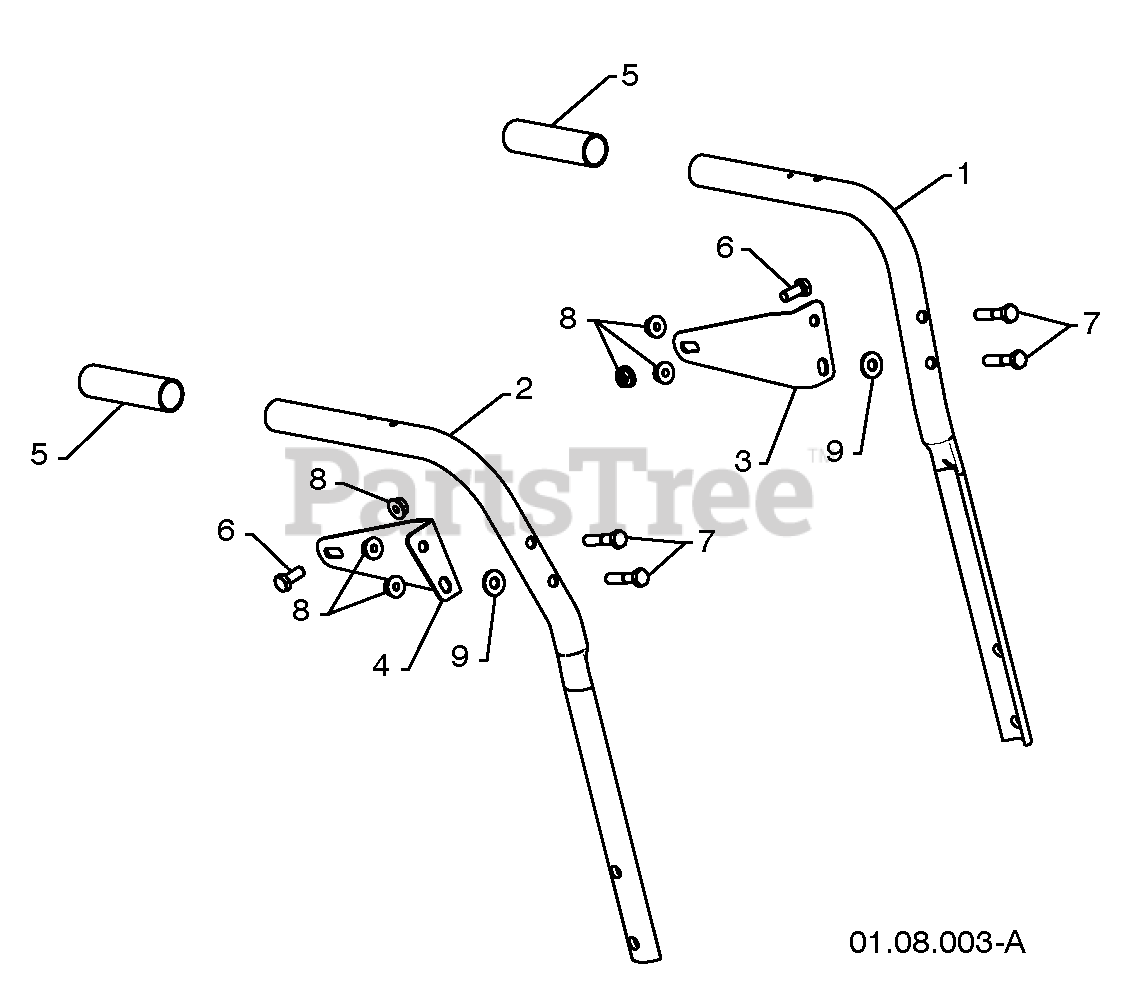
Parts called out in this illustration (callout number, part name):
1	PLOW HANDLE LH
2	PLOW HANDLE RH
3	PANEL BRACKET LH
4	PANEL BRACKET RH
5	HANDLE GRIP
6	SCREW 5/16-18 X .750
7	SCREW 5/16-18 X 1.50
8	NUT 5/16-18
9	WASHER
